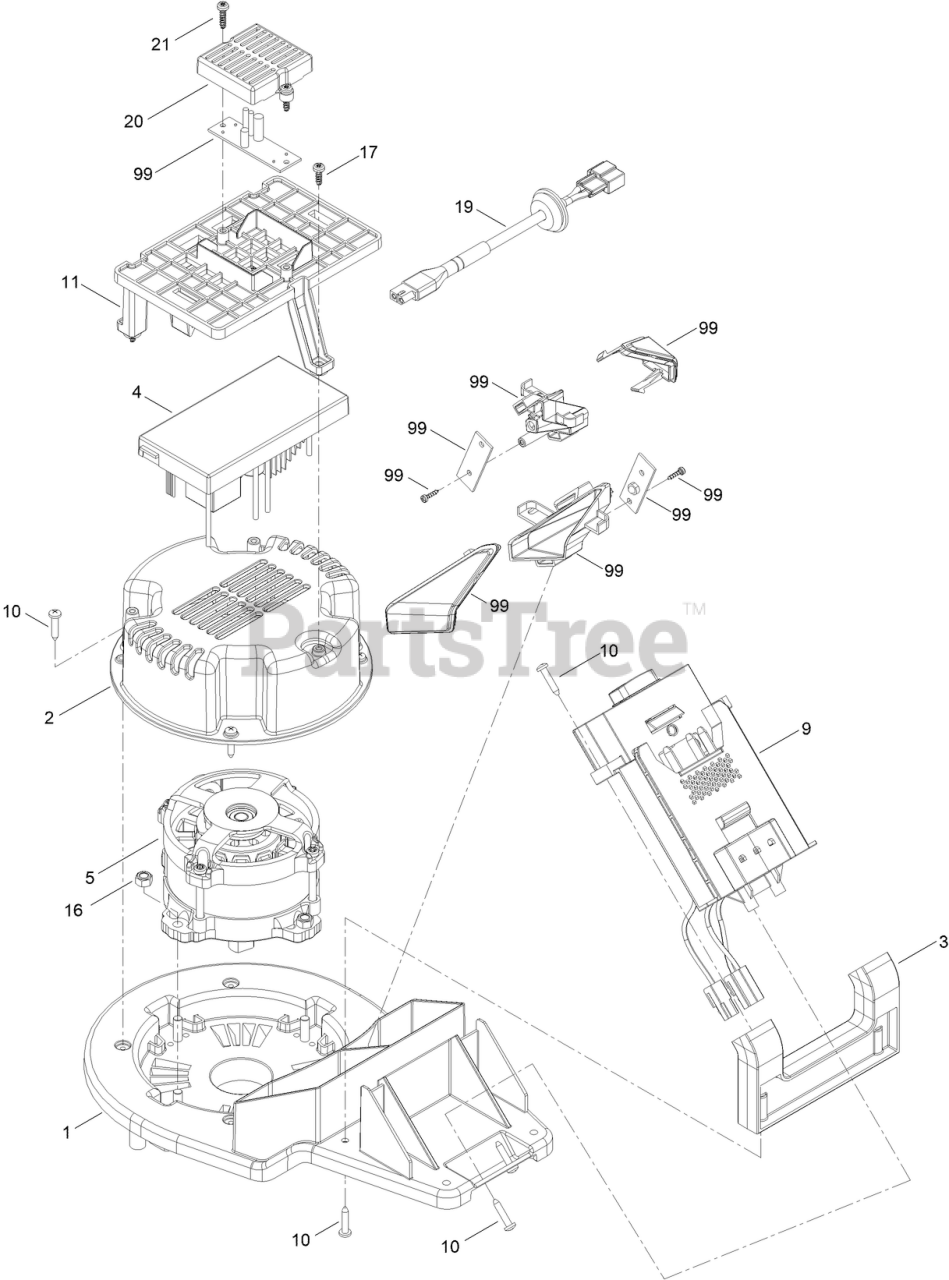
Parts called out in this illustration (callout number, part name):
1	ASM-MOUNT, MOTOR
2	COVER-MOTOR
3	SUPPORT-RECEIVER
4	CONTROLLER-MOTOR, SP LED
5	MOTOR-1KW, 60V
9	BATTERY TRACK ASM
10	SCREW-PPH, ST4.2x20
11	BRKT-CONTROLLER
16	NUT-HEX, M6
17	SCREW-TPH, ST4.2x12
19	ASM-WIRE, COBRA SP
20	COVER-DRIVER, LED
21	SCREW-TPH, ST4.2X16
99	LED Service ASM
